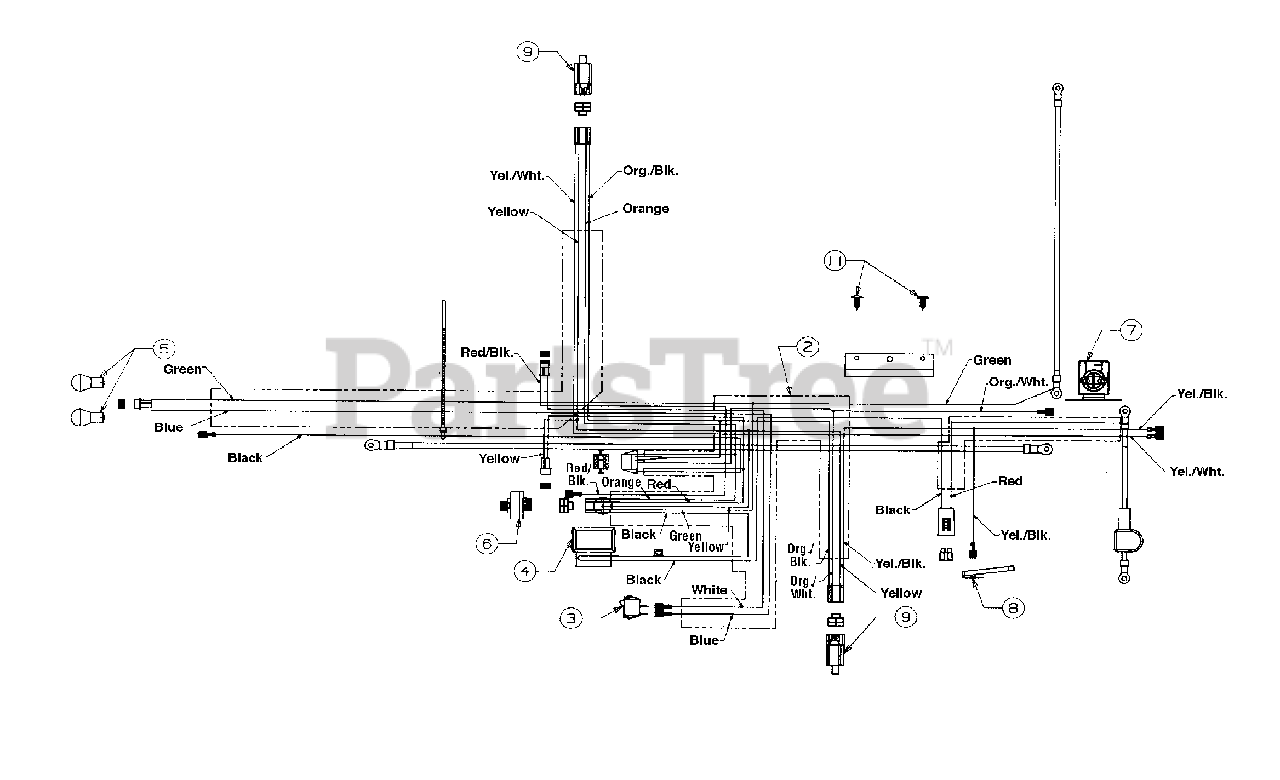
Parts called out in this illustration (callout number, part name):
2	Wire Harness w/Light Switch and Amp
3	Light Switch
4	Ammeter
5	Bulb (Headlight)
6	Ignition Switch
7	Solenoid
8	Safety Switch (Reverse)
9	Safety Switch
11	Ratchet
